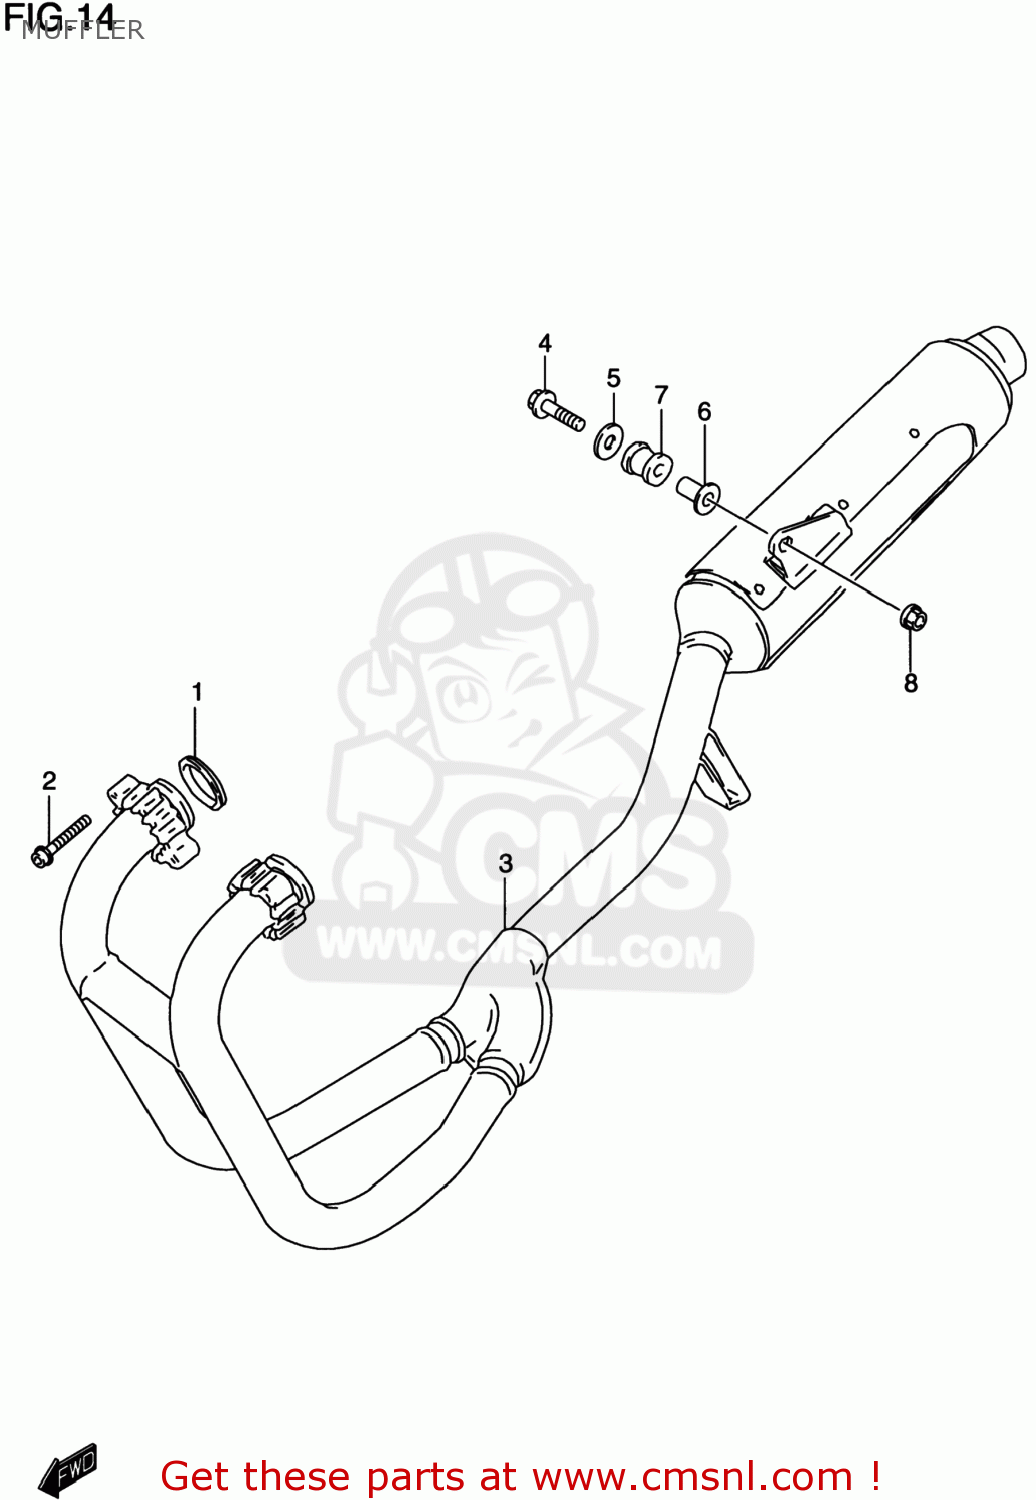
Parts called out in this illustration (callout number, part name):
1	GASKET,EXHAUST PIPE (NAS)
2	BOLT
3	MUFFLER
4	BOLT(8X40)
5	WASHER(8.5X28X1.6)
6	SPACER(8.6X12X24.2)
7	CUSHION
8	NUT
